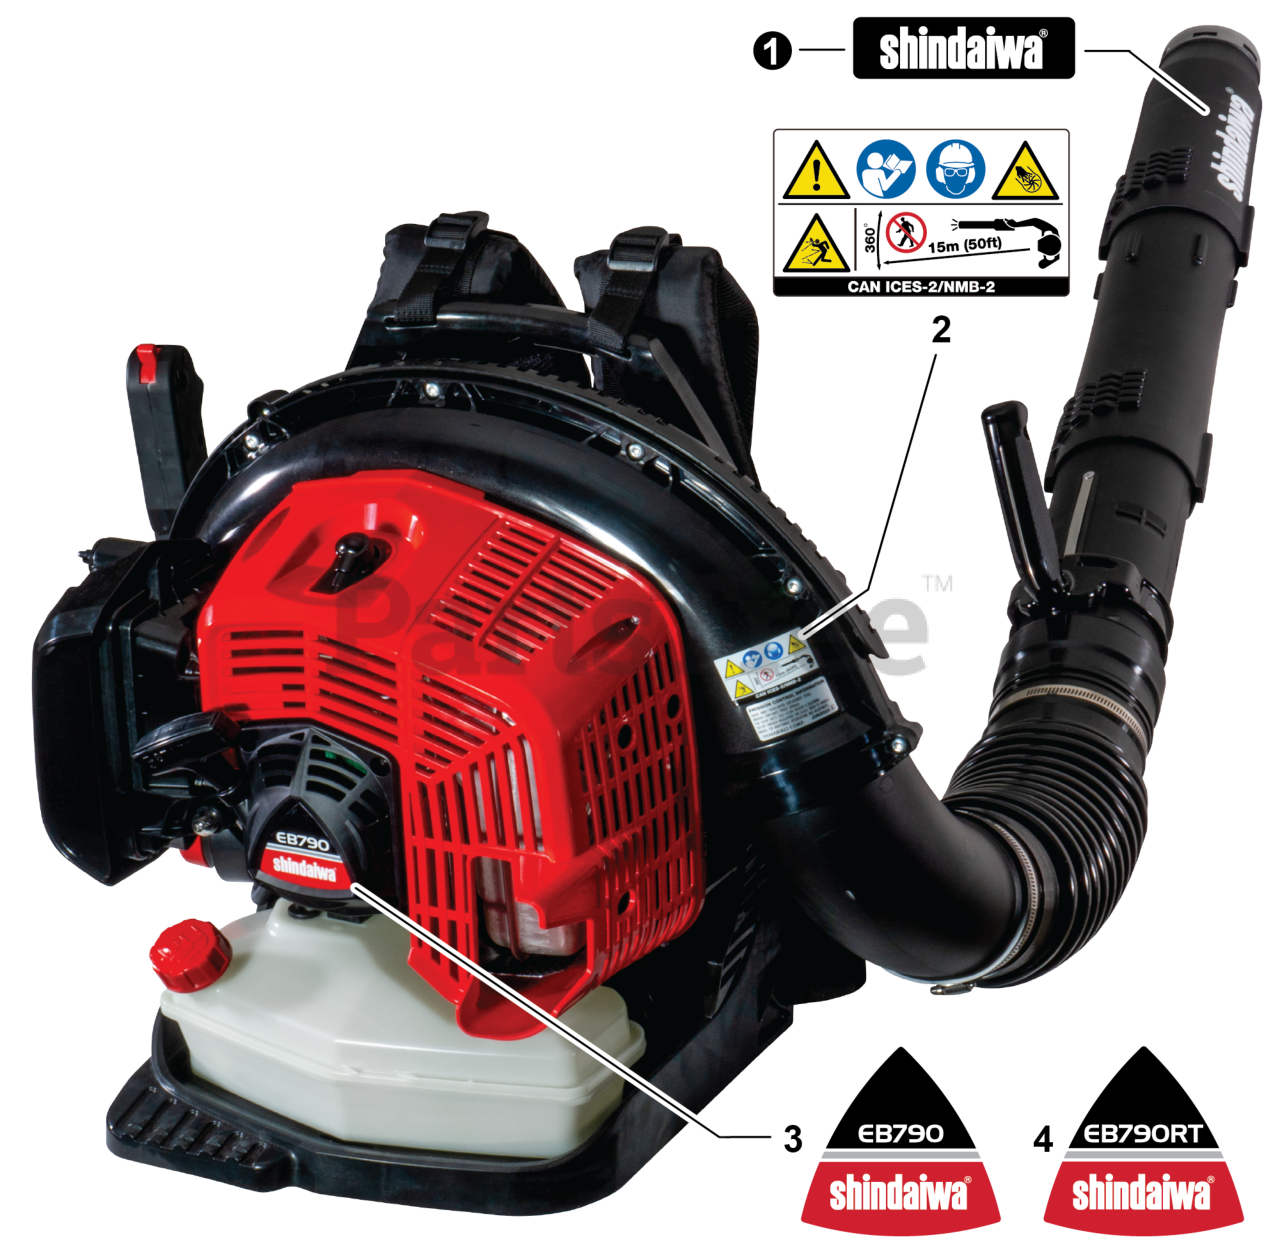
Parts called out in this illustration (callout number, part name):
1	LABEL - SHINDAIWA BLOWER TUBE
2	LABEL - CAUTION
3	LABEL - RECOIL STARTER EB790
4	LABEL - RECOIL STARTER EB790RT
